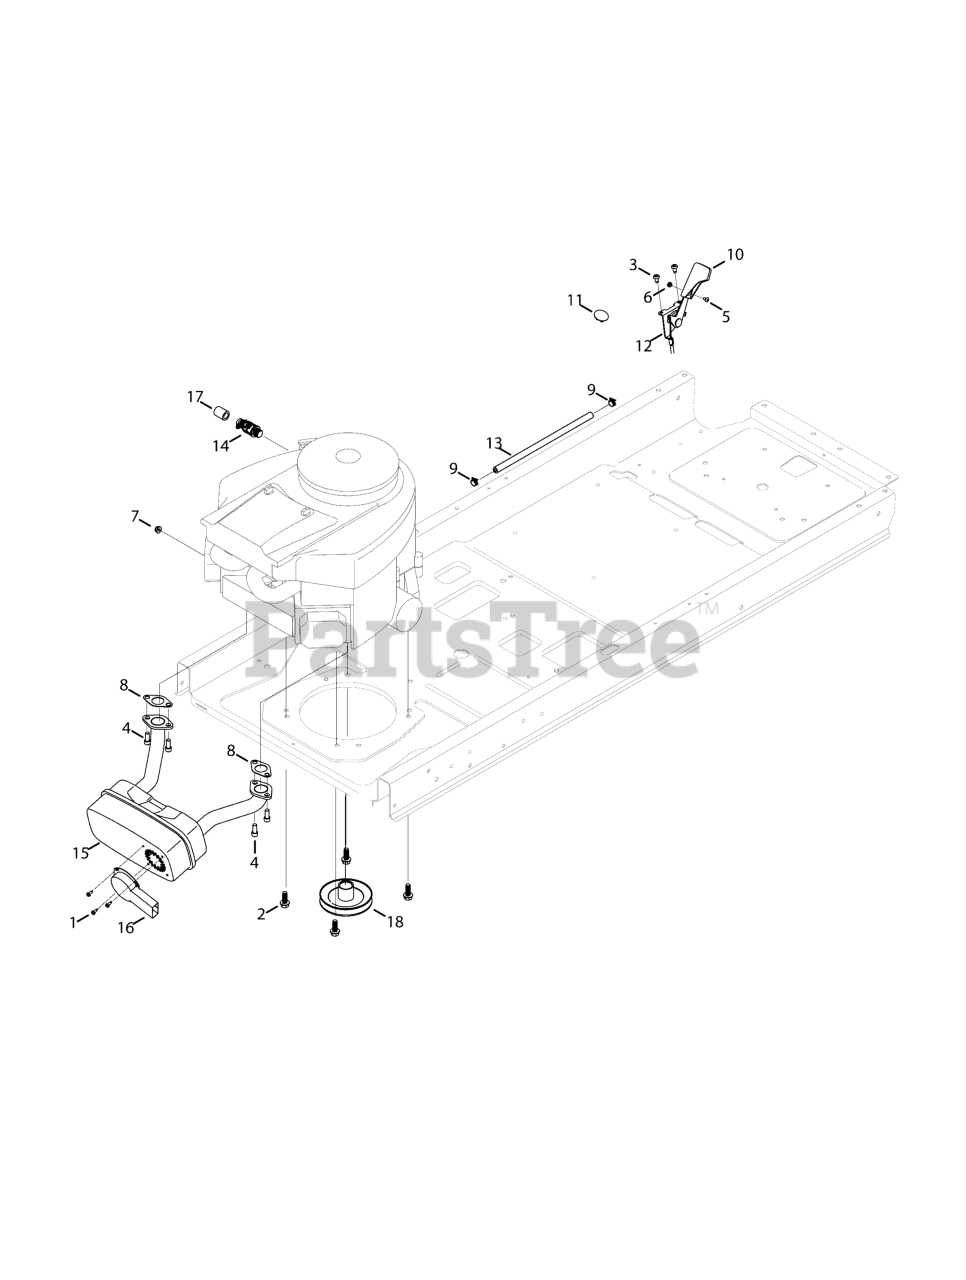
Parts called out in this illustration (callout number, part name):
1	SCREW, #8-18 X .500, Hex Washer
2	SCREW, Engine Mounting, 3/8-16 x 1
3	SCREW, 1/4-20 X .50
4	SCREW, 5/16-18 X .750, Socket Head
5	SCREW, #8-32 X .375
6	NUT, #8-32, Hex
7	NUT, Flange Nylock , 1/4-20
8	GASKET, Exhaust
9	CLAMP, .490 DIA., Hose
10	KNOB, Throttle Control
11	PLUG, Choke
12	CABLE, Throttle/Choke Control
13	HOSE, 1/4, Fuel
14	DRAIN, Oil
15	MUFFLER, Intek Twin
16	DEFLECTOR, Muffler, Long
17	HOSE, Oil Drain
18	PULLEY, Engine
